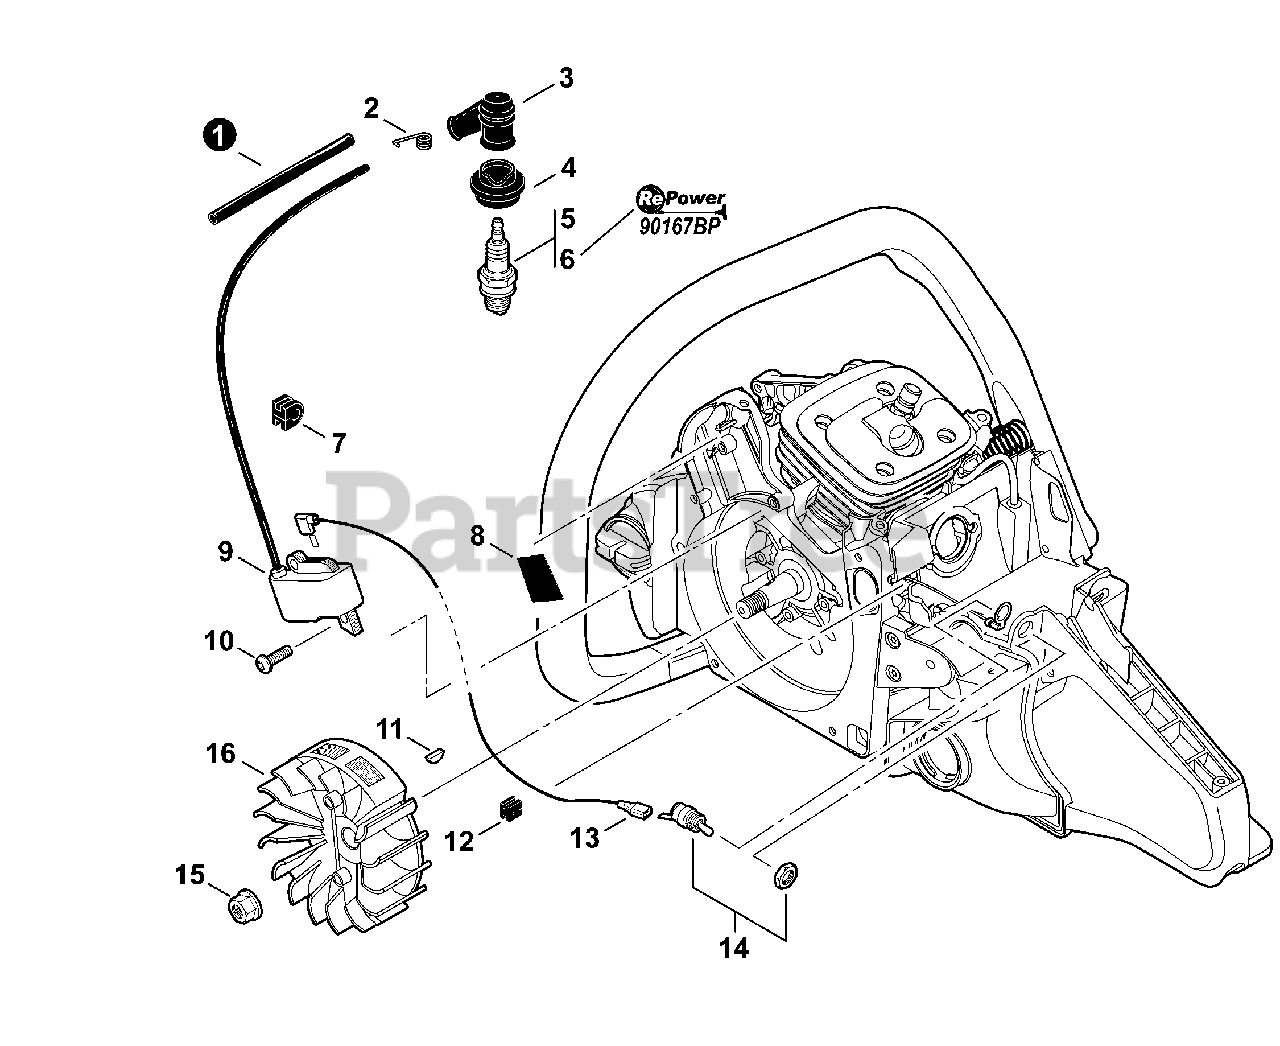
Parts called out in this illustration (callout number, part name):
1	TUBE, IGNITION COIL 6×7.2×70
2	TERMINAL, SPARK PLUG
3	CAP, SPARK PLUG
4	SEAL, SPARK PLUG
5	SPARK PLUG - BPM8Y
6	SPARK PLUG - BPMR8Y
8	CUSHION
9	COIL, IGNITION
10	BOLT, TORX 5×16
11	KEY, WOODRUFF
12	GROMMET, LEAD
13	LEAD - IGNITION L= 280
14	SWITCH, ON-OFF
15	NUT, FLANGE M8
16	FLYWHEEL
